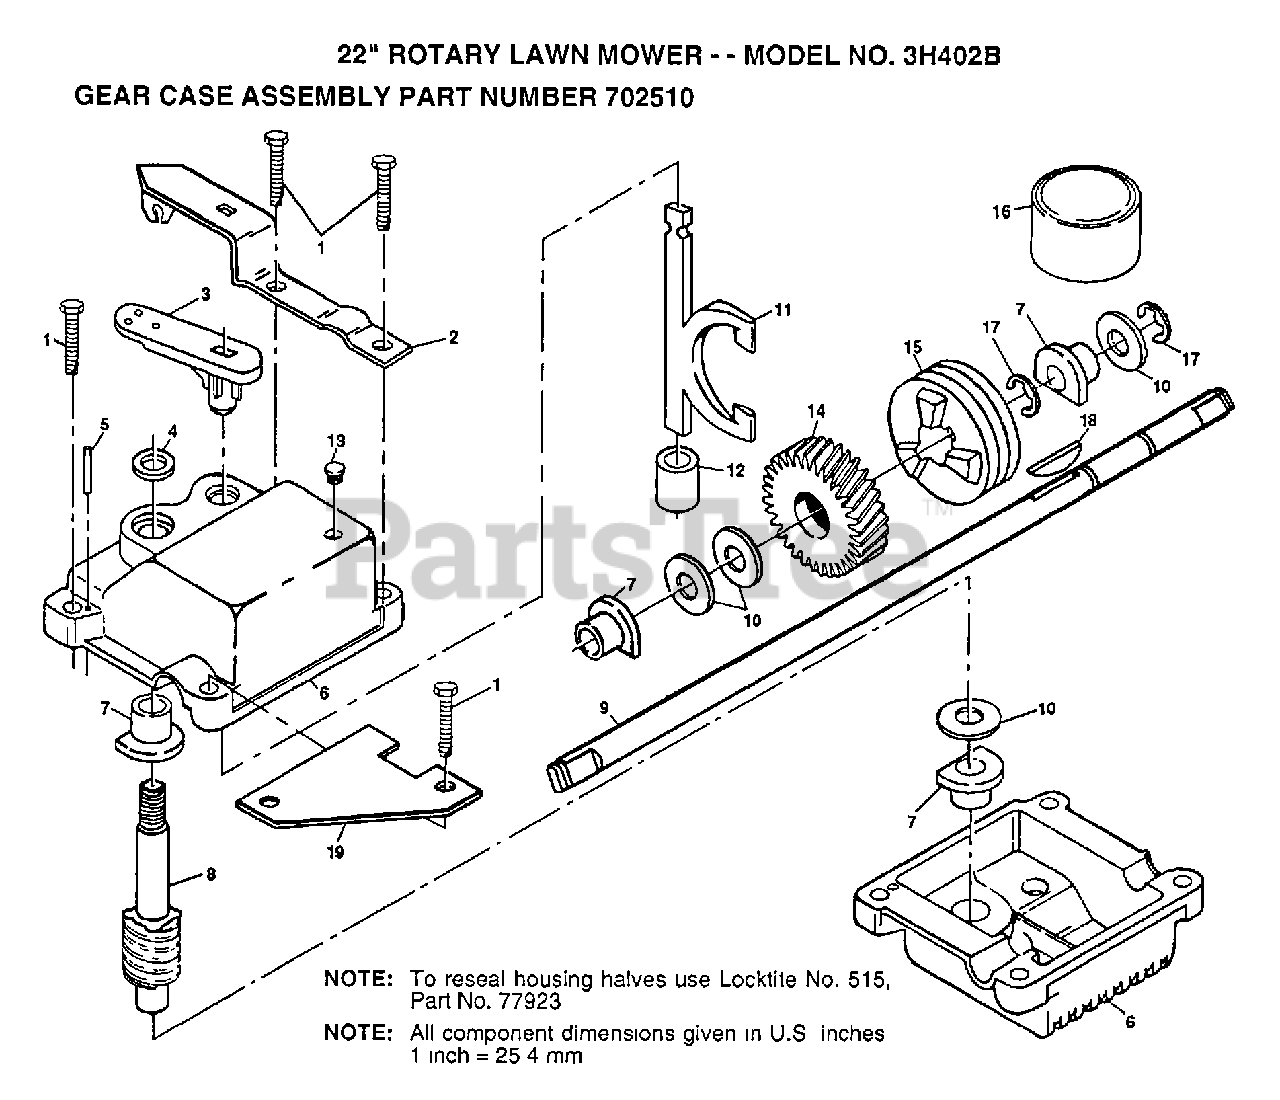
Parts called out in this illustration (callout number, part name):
1	SCREW.1/4-20
2	BRACKET.GEARCASE
3	SHIFTER
4	SEAL
5	PIN GROOVED 1/8X5
6	KIT GEARCASE HALV
7	BEARING
8	SHAFT.WORM
9	SHAFT.DRIVE.SD
10	THRUST WASHER
11	CLUTCH YOKE
12	BUSHING.GEAR BOX
13	PLUG PM
14	GEAR.HELICAL
15	CLUTCH JAW
17	RING T
18	HI PRO KEY
